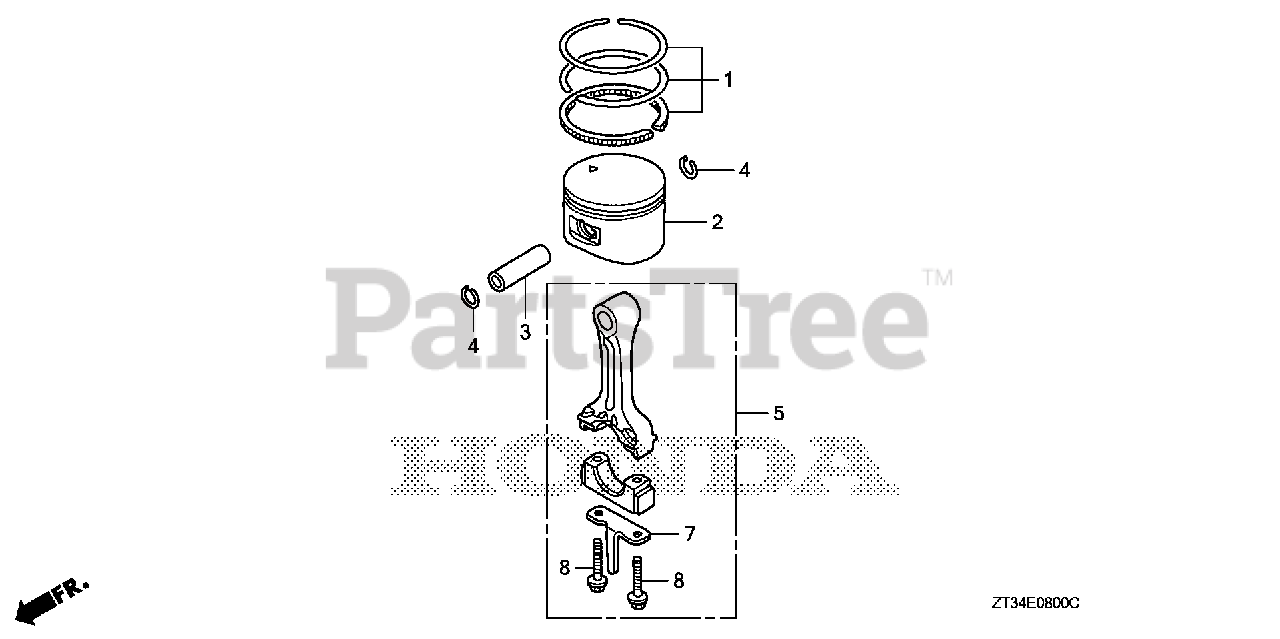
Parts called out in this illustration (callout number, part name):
1	RING SET, PISTON (STD)
2	PISTON (STD)
3	PIN, PISTON
4	CLIP, PISTON PIN (10MM)
5	ROD ASSY., CONNECTING
7	DIPPER, CONNECTING ROD
8	BOLT, CONNECTING ROD
